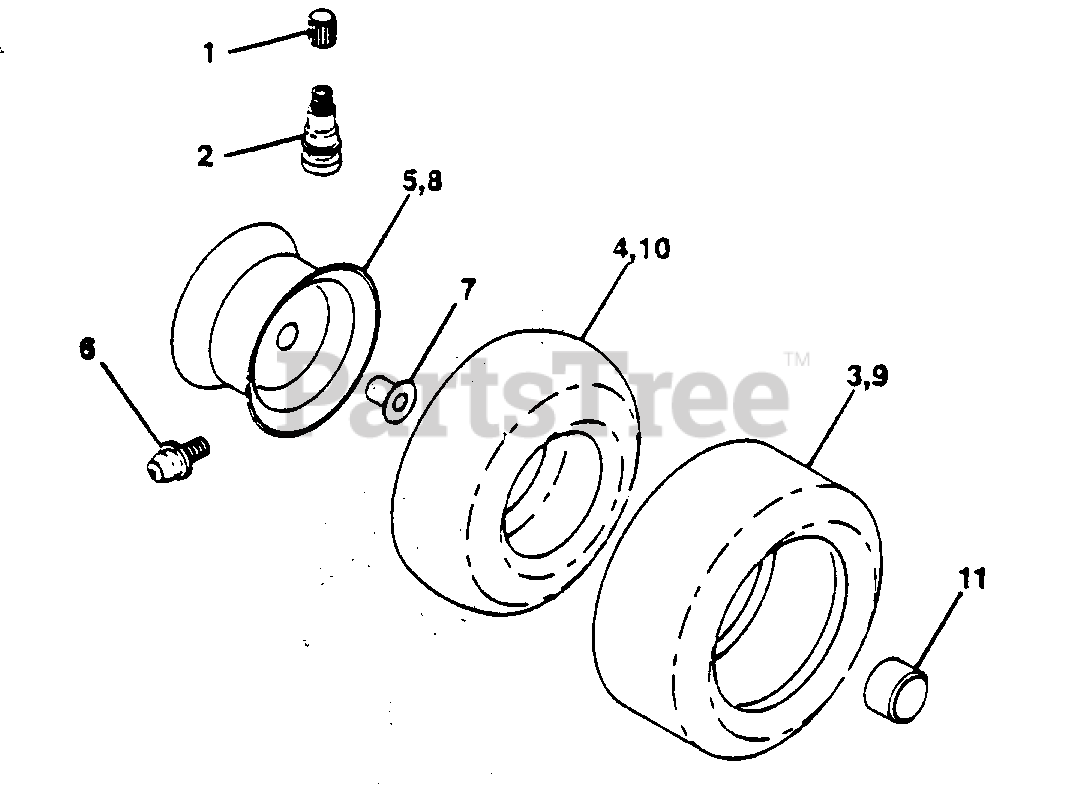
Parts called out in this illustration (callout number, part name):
1	Cap Valve Tire
3	Tire F Ts 15 X 60 - 6 Service
4	Tube Front (Service Item Only)
5	Rim Asm 8"rear Silver Service
6	Fitting Grease (Front Wheel Only)
7	Bearing Flange (Front Wheel Only)
8	Rim Asm 6" front Silver Service
9	Tire R Ts 20 10 C Service
10	Tube Rear (Service Item Only)
